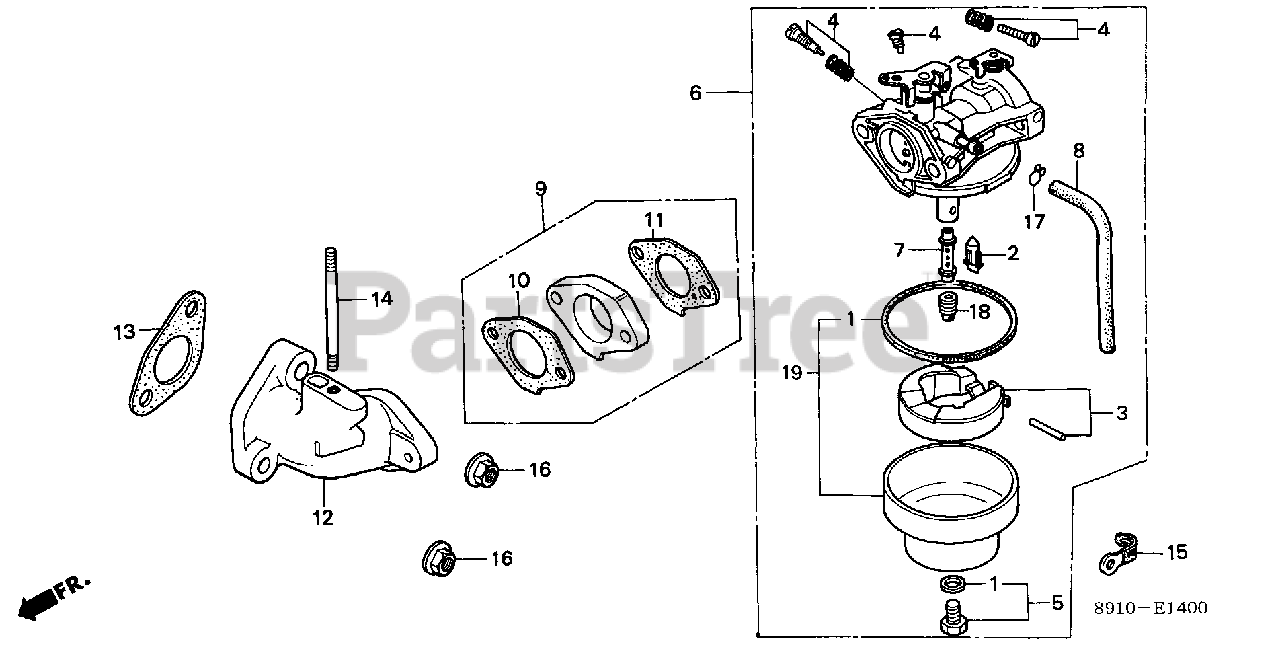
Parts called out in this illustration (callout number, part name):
1	GASKET SET (CARBURETOR NO.)
2	VALVE SET, FLOAT
3	FLOAT SET (CARBURETOR NO.)
4	SCREW SET A (CARBURETOR NO.)
4	SCREW SET A
5	SCREW SET
6	CARBURETOR ASSY. (BB38A H)
7	NOZZLE, MAIN
9	INSULATOR, CARBURETOR
10	GASKET, INSULATOR (NOT AVAILABLE)
11	GASKET, CARBURETOR
12	MANIFOLD, IN.
13	GASKET, IN. MANIFOLD
14	BOLT, STUD (6X87)
16	NUT, FLANGE (8MM)
18	JET, MAIN (#92)
18	JET, MAIN (#95)
18	JET, MAIN (#98)
18	JET, MAIN (#100)
18	JET, MAIN (#102)
18	JET, MAIN (#105)
19	CHAMBER SET, FLOAT
